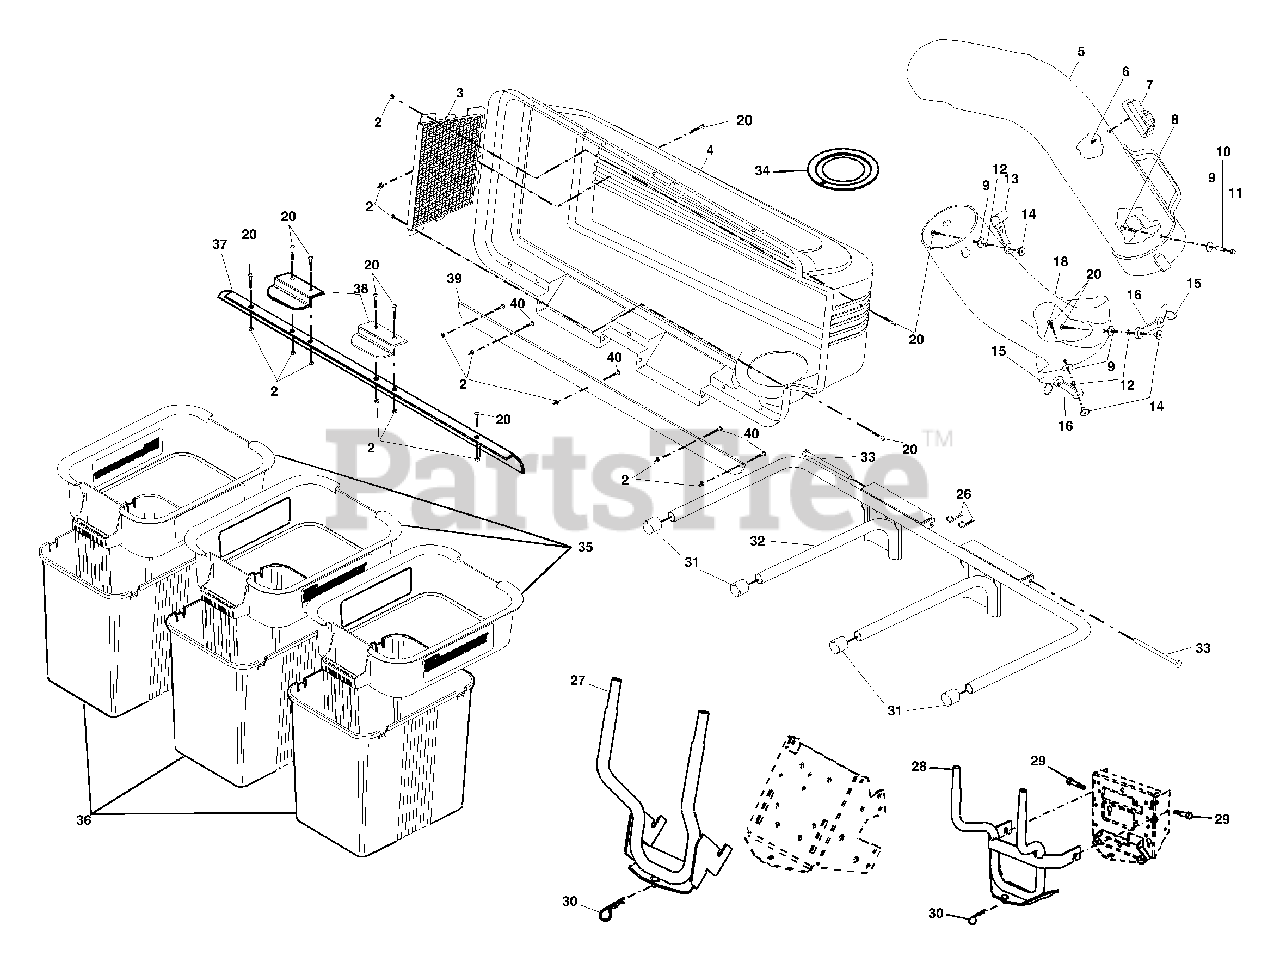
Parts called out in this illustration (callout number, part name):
2	Nut, Crownlock #10-24
3	Screen, Cover
4	Cover Assembly
5	Chute, Upper
6	Screw, Special #10-14x1/2
7	Dump Bag Indicator
8	Screw, #10-24 x 1-1/8
9	Washer 3/16x3/4x16 Ga.
10	Spacer, Split
11	Nut, Acorn #10-24
12	Washer, Lock
13	Latch, Chute
14	Nut, Weld
15	Latch, Hook
16	Rubber, Latch
18	Chute, Lower
20	Screw #10-24 x 5/8
26	Spring, Retainer
27	Support Assembly - GT
28	Support Assembly - LT
29	Shoulder Bolt,Self Tapping
30	Spring, Retainer
31	Plug, Tubing End
32	Bagger, Frame
33	Pin, Hinge
34	Gasket, Cover
35	Container, Top
36	Container, Bottom
37	Seal, Cover
38	Latch Handle, Cover
39	Strip, Reinforcement
40	Screw #10-24 x 1/2
